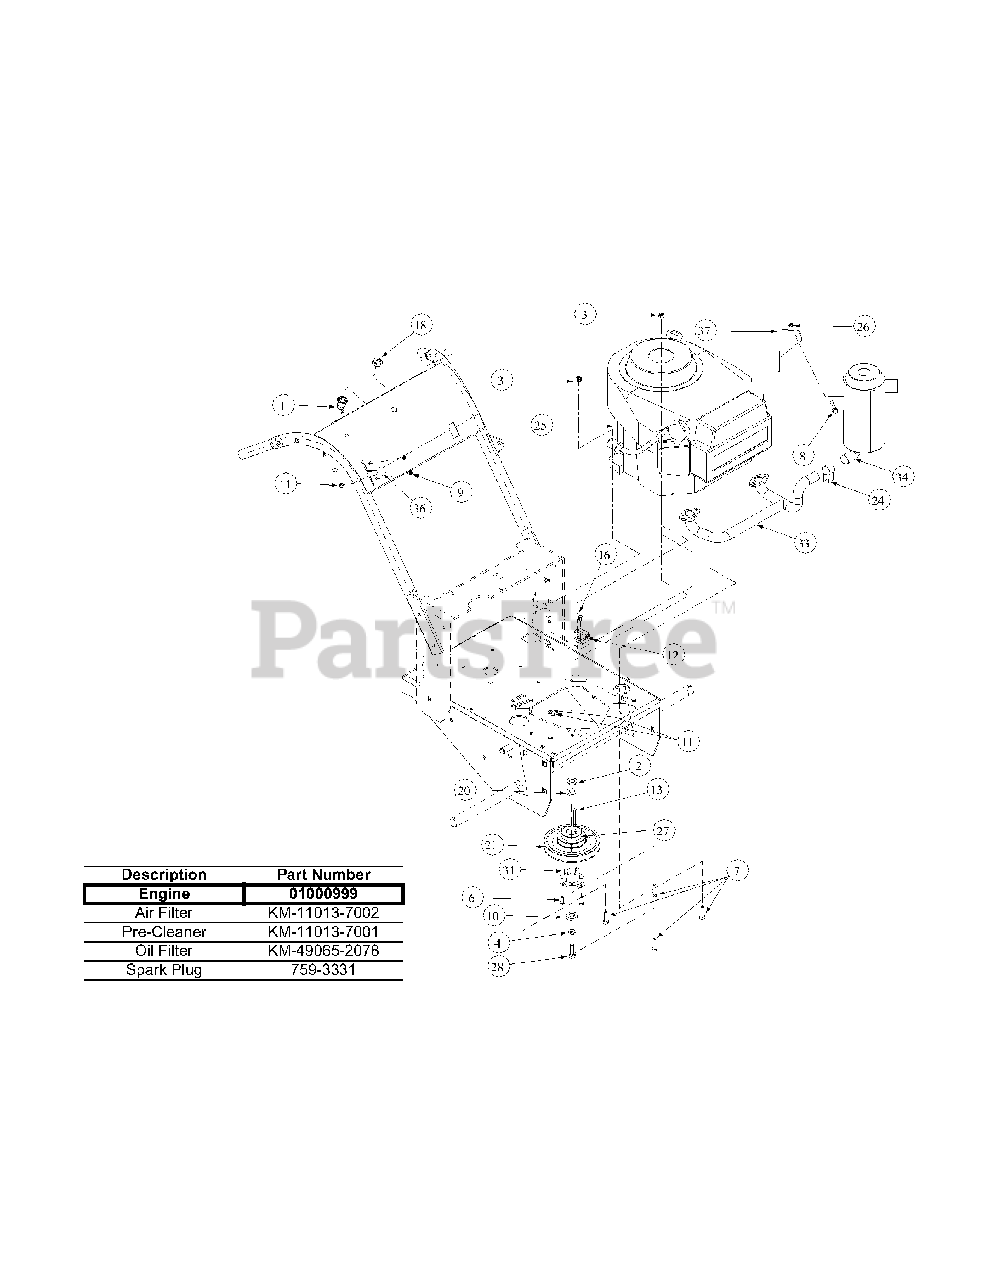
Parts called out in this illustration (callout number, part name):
1	Single Ignition ON/OFF Switch
2	Engine Pulley Spacer
3	Nylock Nut, 5/16-18
4	Lock Washer
6	Hex Cap Screw, 1/4-20, .75
7	Hex Cap Screw, 5/16-18 x 2
8	Hex Cap Screw, 5/16-18 x 3/4
9	Screw, Hex Washer, 10-32 x 1/2
10	Clutch Washer
11	Lock Nut, Nylon Insert, 10-32
12	Delta Switch,
13	Key Stick, 1/4 x 1/4 x 2-3/4
14	Harness Wire
16	Machine Screw, 10-32 x 5/8
18	Nut, w/Cap, 5/8-32 Ignition
20	Flat Washer
21	Deck Pulley
22	Belt
24	Muffler Clamp Assembly
25	17HP Kawasaki Engine
26	Hex Nut Centerlock, 5/16-18
27	Traction Pulley
28	Hex Cap Screw, 7/16-20 x1-1/4
32	Harness Hourmeter
33	Kawasaki Manifold
34	Kawasaki Muffler
36	Control Throttle, 42.25
37	Kawasaki Muffler Bracket
